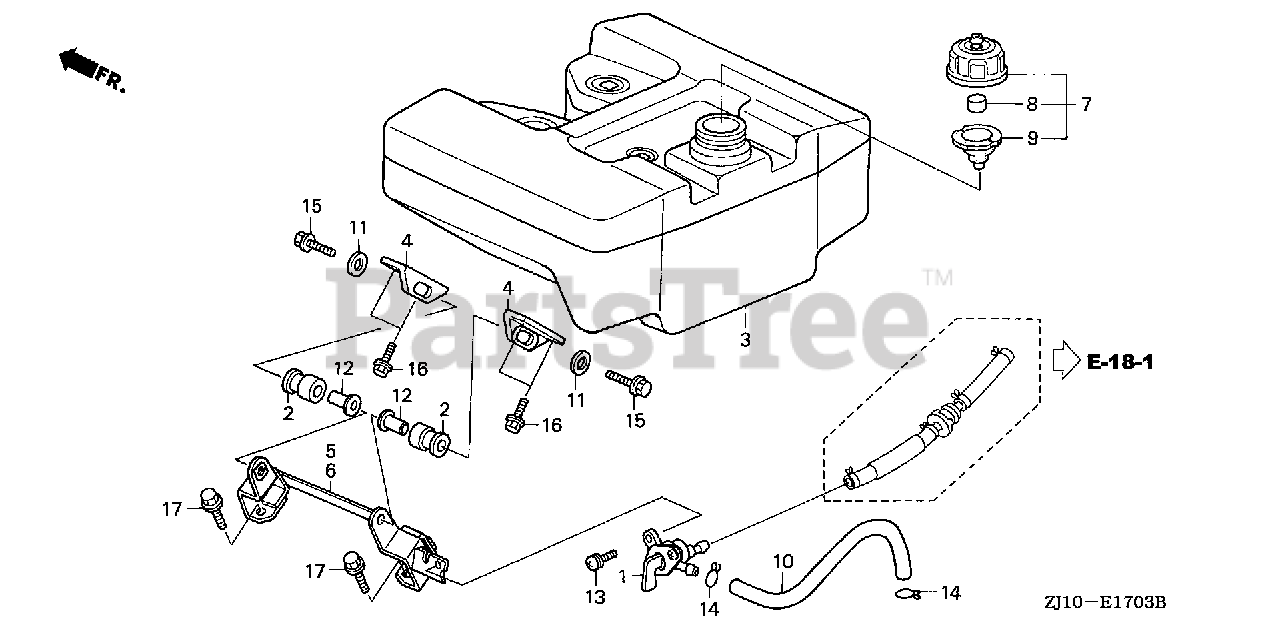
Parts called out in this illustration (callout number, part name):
1	PETCOCK ASSY.
2	RUBBER, TANK MOUNTING
3	TANK, FUEL
4	BRACKET, FUEL TANK
5	STAY, R. FUEL TANK
6	STAY, L. FUEL TANK
7	CAP ASSY., FUEL TANK
8	SPONGE, FUEL CAP BREATHER
9	GASKET, FUEL CAP
10	TUBE, FUEL
11	WASHER, PLAIN (6MM)
12	COLLAR, TANK SETTING
13	SCREW-WASHER (5X14)
14	CLIP, TUBE (B10)
15	BOLT, FLANGE (6X45)
16	BOLT, FLANGE (6X16)
17	BOLT, FLANGE (8X20)
